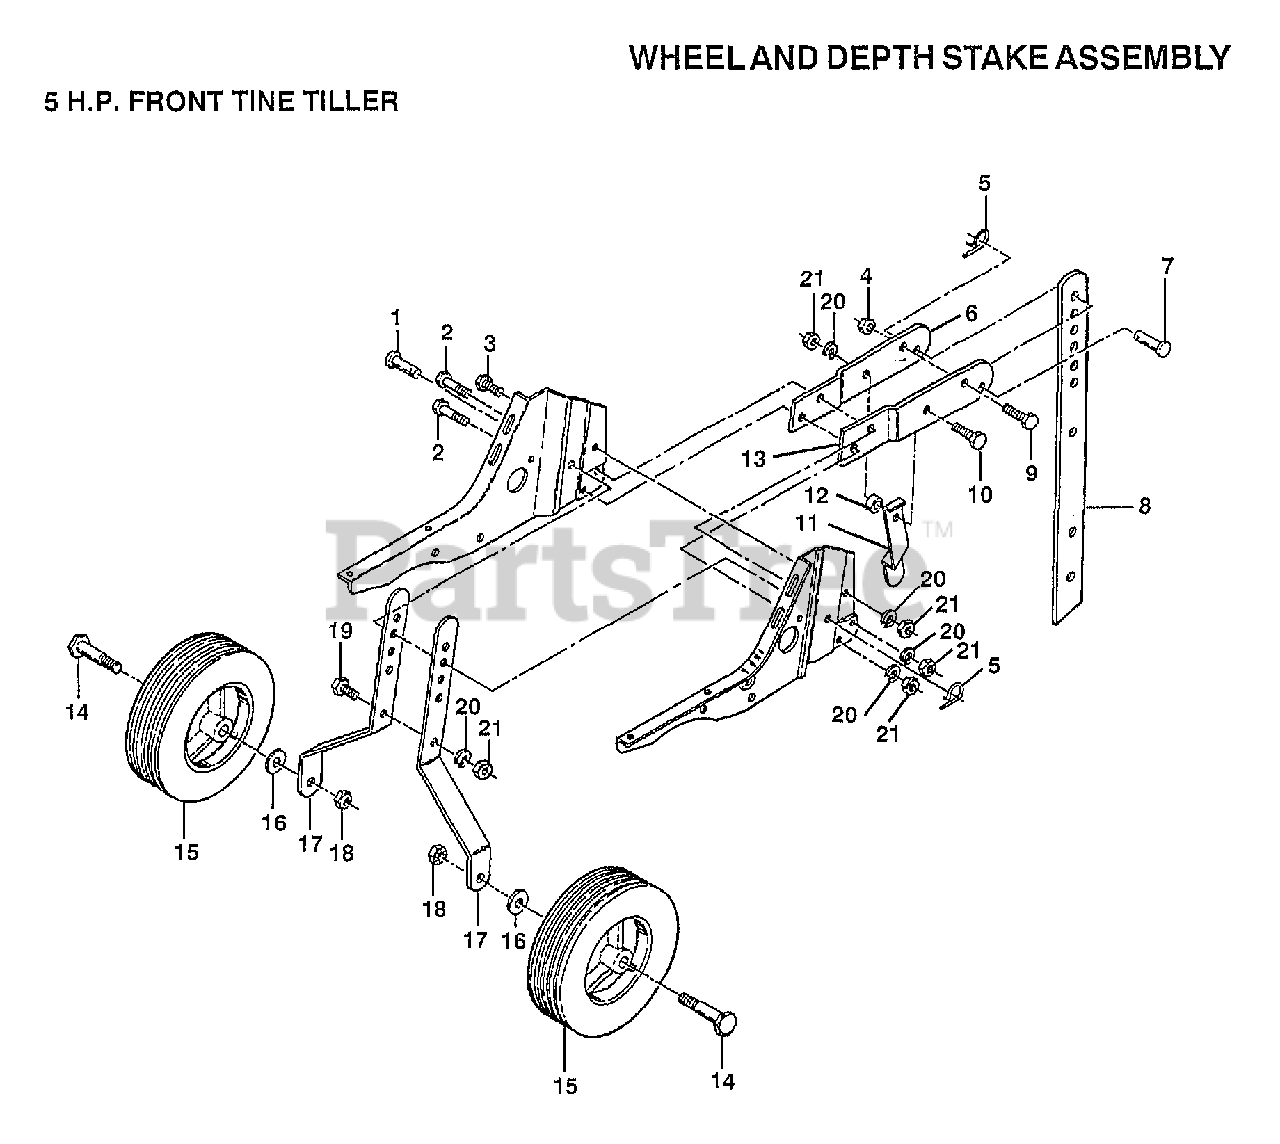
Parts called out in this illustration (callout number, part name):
1	DRILLED RIVET RT
3	BOLT
4	GRIPCO NUT
5	SPRING.RETAINER
9	BOLT.3/8-24X1-1/2
10	BOLT.HEX.5/16-1.5
11	STAKE SPRING TI
12	WASHER
14	BOLT SHOULDER
15	WHEEL TI
16	WASHER
20	LOCKWASHER
21	NUT.HEX.5/16-18
